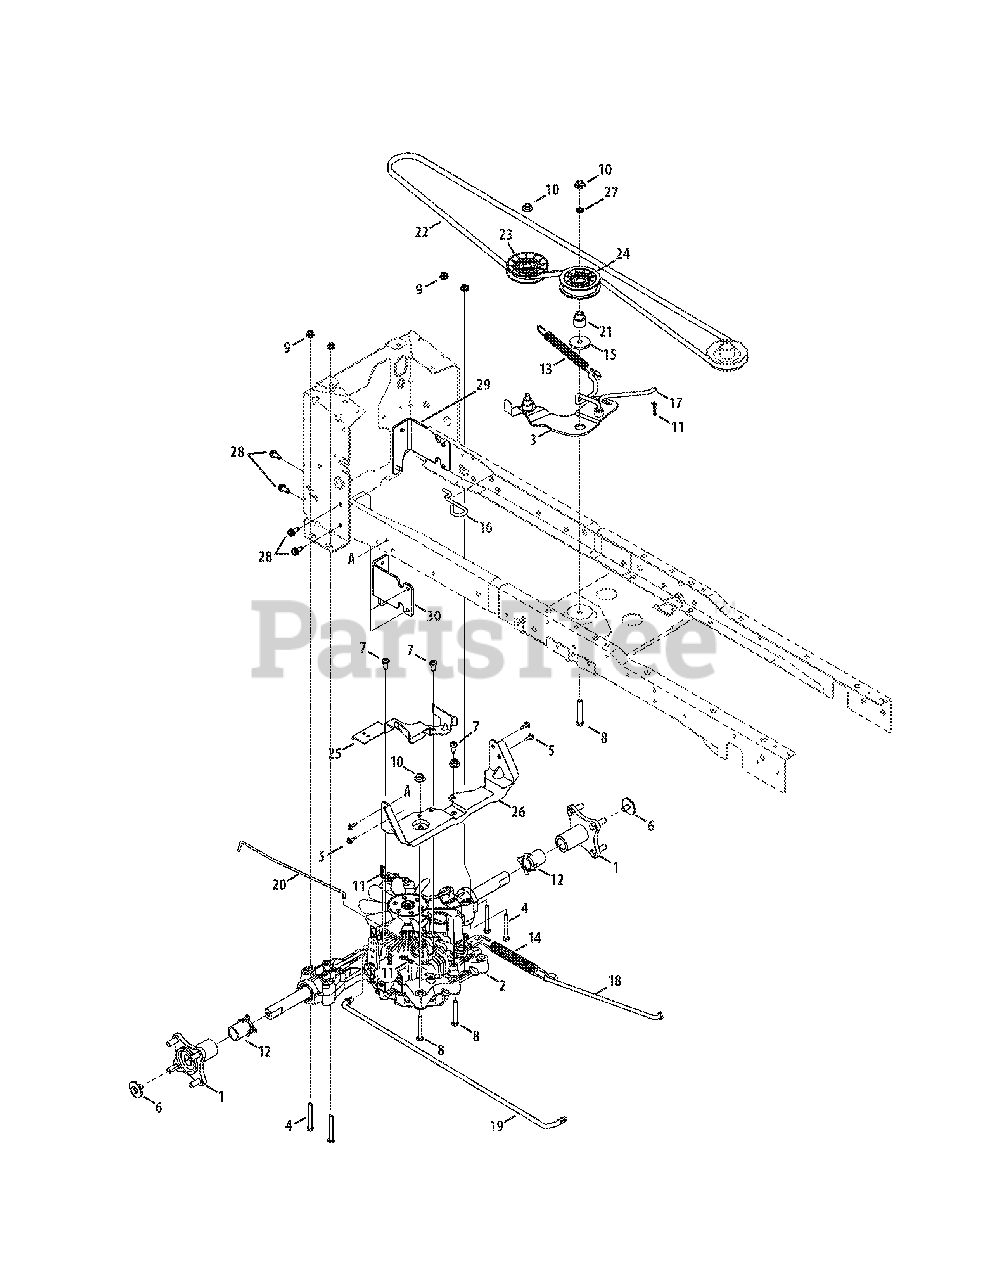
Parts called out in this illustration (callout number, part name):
1	Hub Assembly, Wheel
2	Transmission Assembly
3	Idler bracket Assembly
4	Hex Screw, 5/16-18, 2.75, Gr5, Std
5	Screw, M6-1 x .625
6	Hex Cap Screw, 3/8-16 x .750
7	Screw, Self-tapping, 5/16-18, 0.750
8	Hex Screw, 3/8-16, 2.25, Gr5
9	Nut, Flange Lock, 5/16-18, Nylon
10	Flange Lock Nut, 3/8-16
11	Pin, Cotter, Bow-Tie 72
12	Sleeve, 1.02 ID x 1.75
13	Spring, Extension, .700 Dia x 8.41
14	Spring, Extension, .90 Dia x 8.14
15	Shoulder Spacer, .884 x .190
16	Deck Spring Rod
17	Idler Link
18	Rod, Brake, Tuff Torq
19	Rod, Control, Tuff Torq
20	Rod, Transmission, Bypass
21	Shoulder Spacer
22	Belt, V-Type
23	Idler Pulley, 3.56 OD
24	Idler Pulley, 3.00 OD
25	Belt Keeper Bracket
26	Transmission Bracket
27	Speed Nut
28	Screw, Self-tapping, 5/16-18, 0.750,
29	Frame Support Bracket, LH
30	Frame Support Bracket, RH
